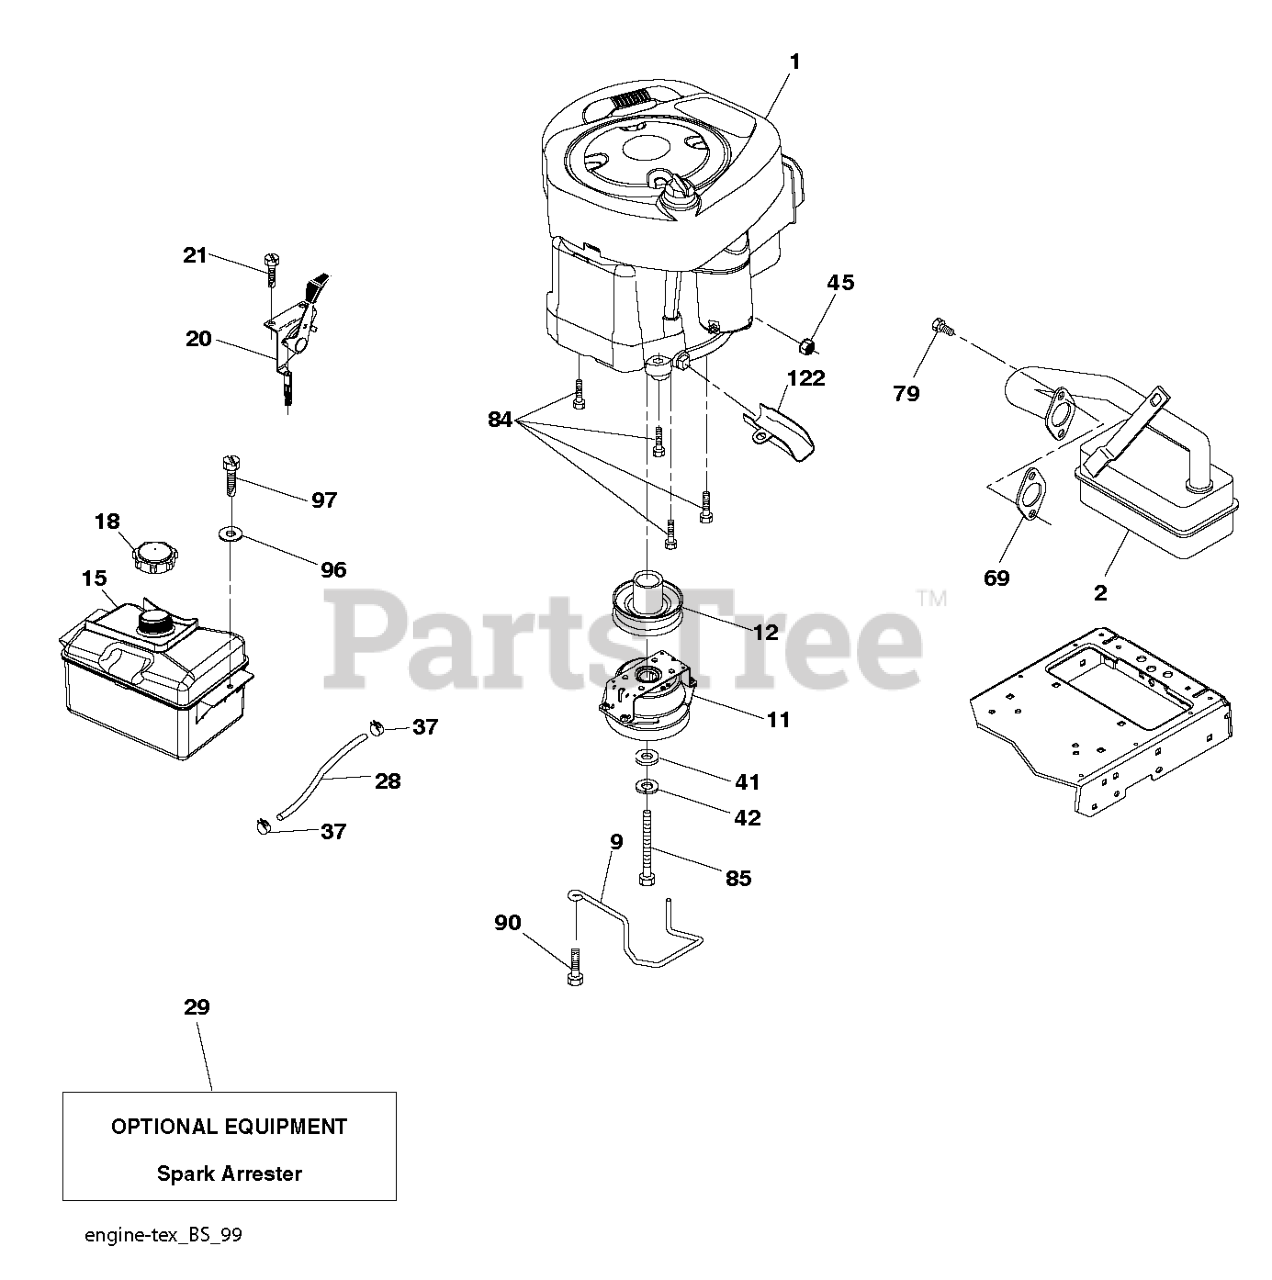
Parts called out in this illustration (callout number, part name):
2	MUFFLER.LT.BRIGGS.14HP.IC/OHV
9	KEEPER.BELT.ENGINE.3.25 (3 2)
11	RB.CLUTCH.OGURA.4.4.PD
12	PULLEY.ASM.ENG.OGURA.3
15	FUEL.TANK.ASM.NON-EPA
18	CAP ASM.FUEL.2.25"FR.
20	CONTROL.TH/CK.C.
21	SCREW.#10 X 0.750.BOS
28	LINE.FUEL.20
29	KIT.SPARK ARRESTOR 794945 B&S
37	HOSE CLAMP
42	LOCKWASHER
45	NUT
69	REPL BY 532 27 22-93
79	SCREW.SOCKET HD.5/16-1
84	SCREW.3/8-16
85	BOLT HEX 7/16-20X4-1/4"
90	SCREW 3/8-16X1
96	WASHER
97	SCREW HEXWSHR 1/4-20X3/4
122	EXTENSION DRAIN OIL
